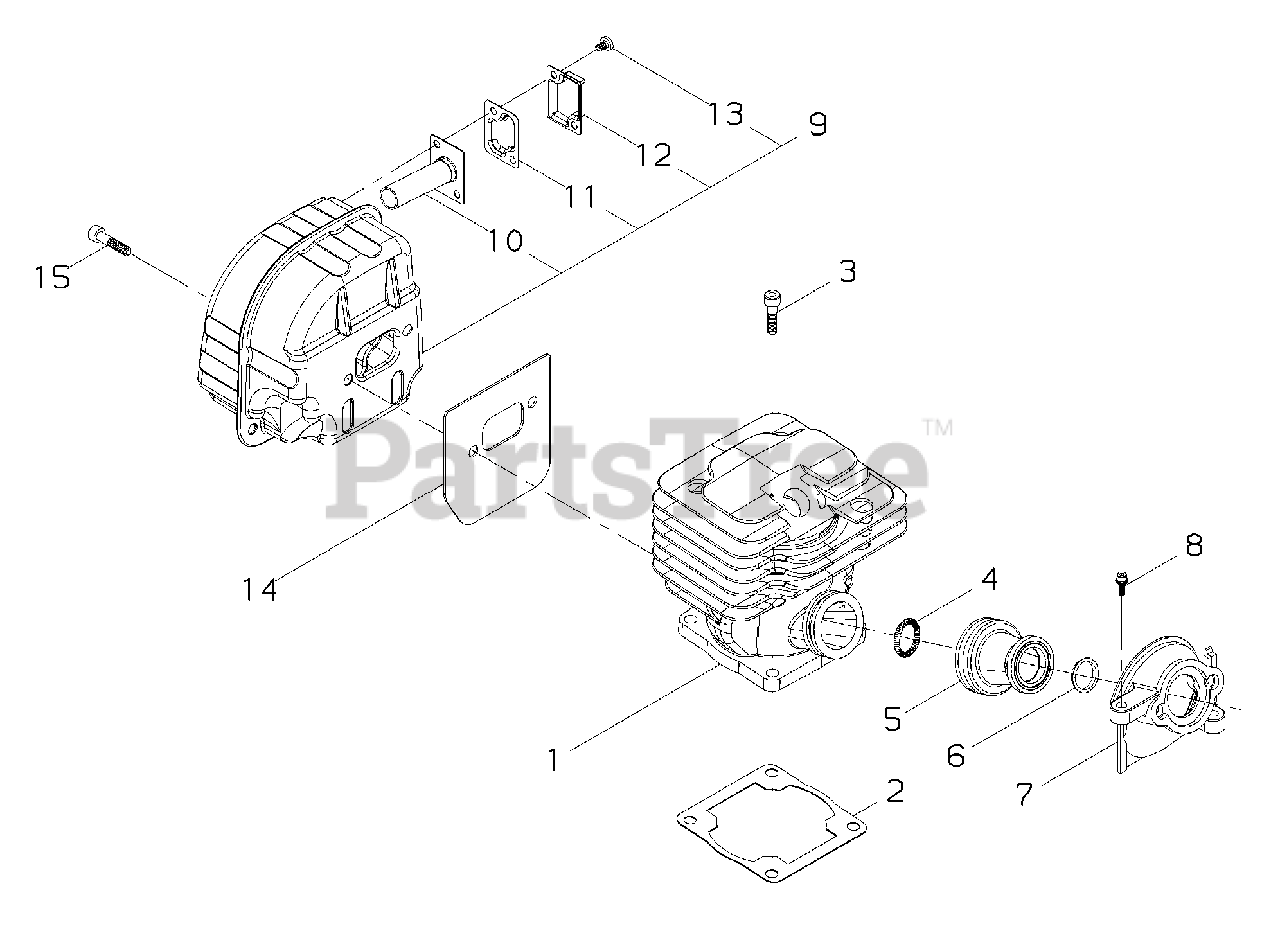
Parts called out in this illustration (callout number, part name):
1	CYLINDER
2	GASKET, CYLINDER
3	SCREW - 5X18
4	SPRING
5	BOOT, INTAKE
6	SLEEVE
7	BRACKET, INTAKE
8	SCREW - 4X16
9	MUFFLER ASSY
10	GUIDE, EXHAUST
11	SCREEN, SPARK ARRESTOR
12	GUIDE, EXHAUST
13	SCREW - 4X6
14	SHIELD, EXHAUST
15	SCREW - 5X18
